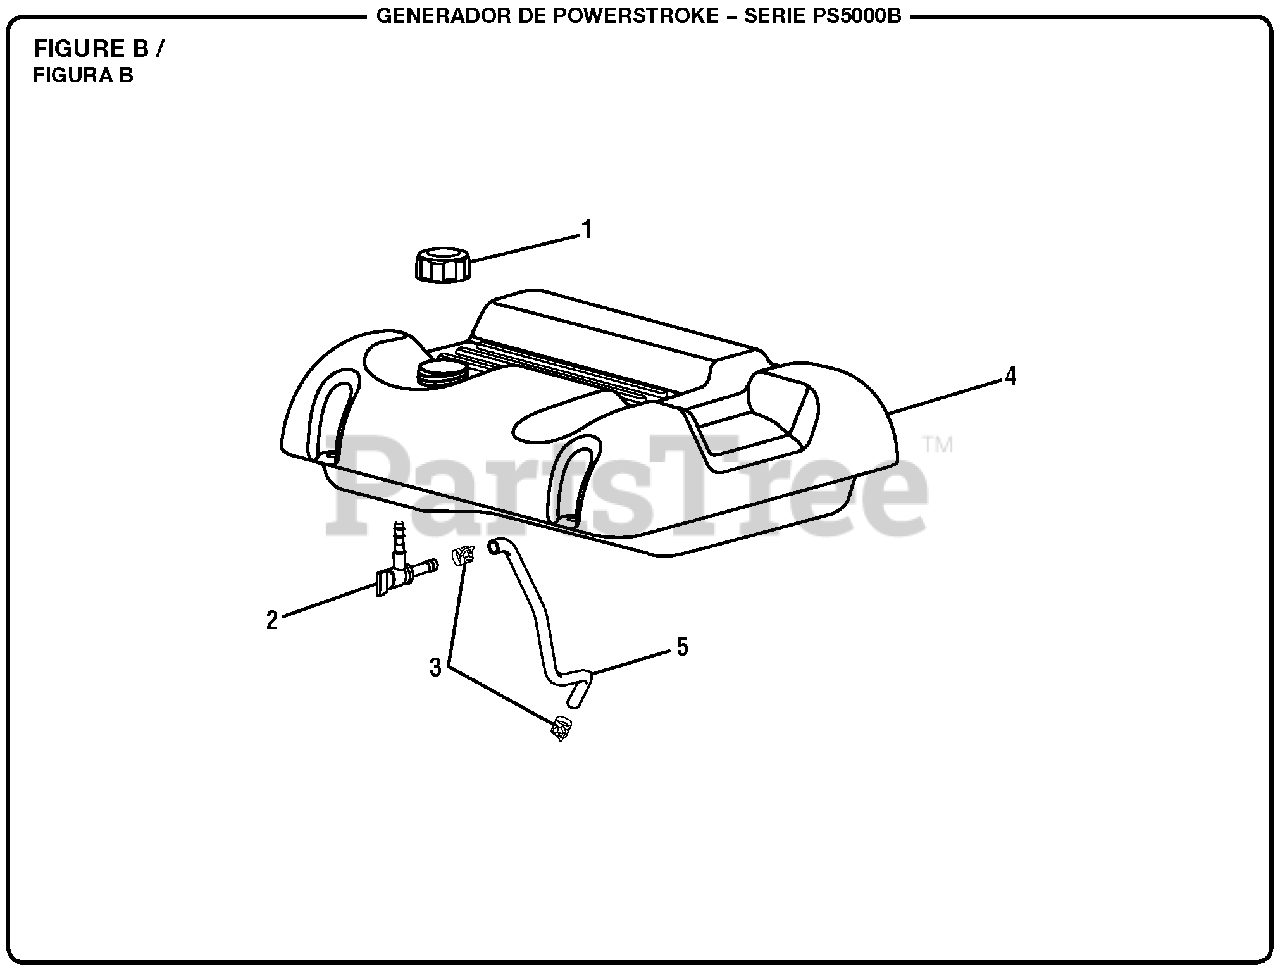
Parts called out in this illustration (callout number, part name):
2	Fuel Shut Off Valve w/
3	Fuel Line Clamp (3/8 in.)
4	Fuel Tank
5	Fuel Line Hose
